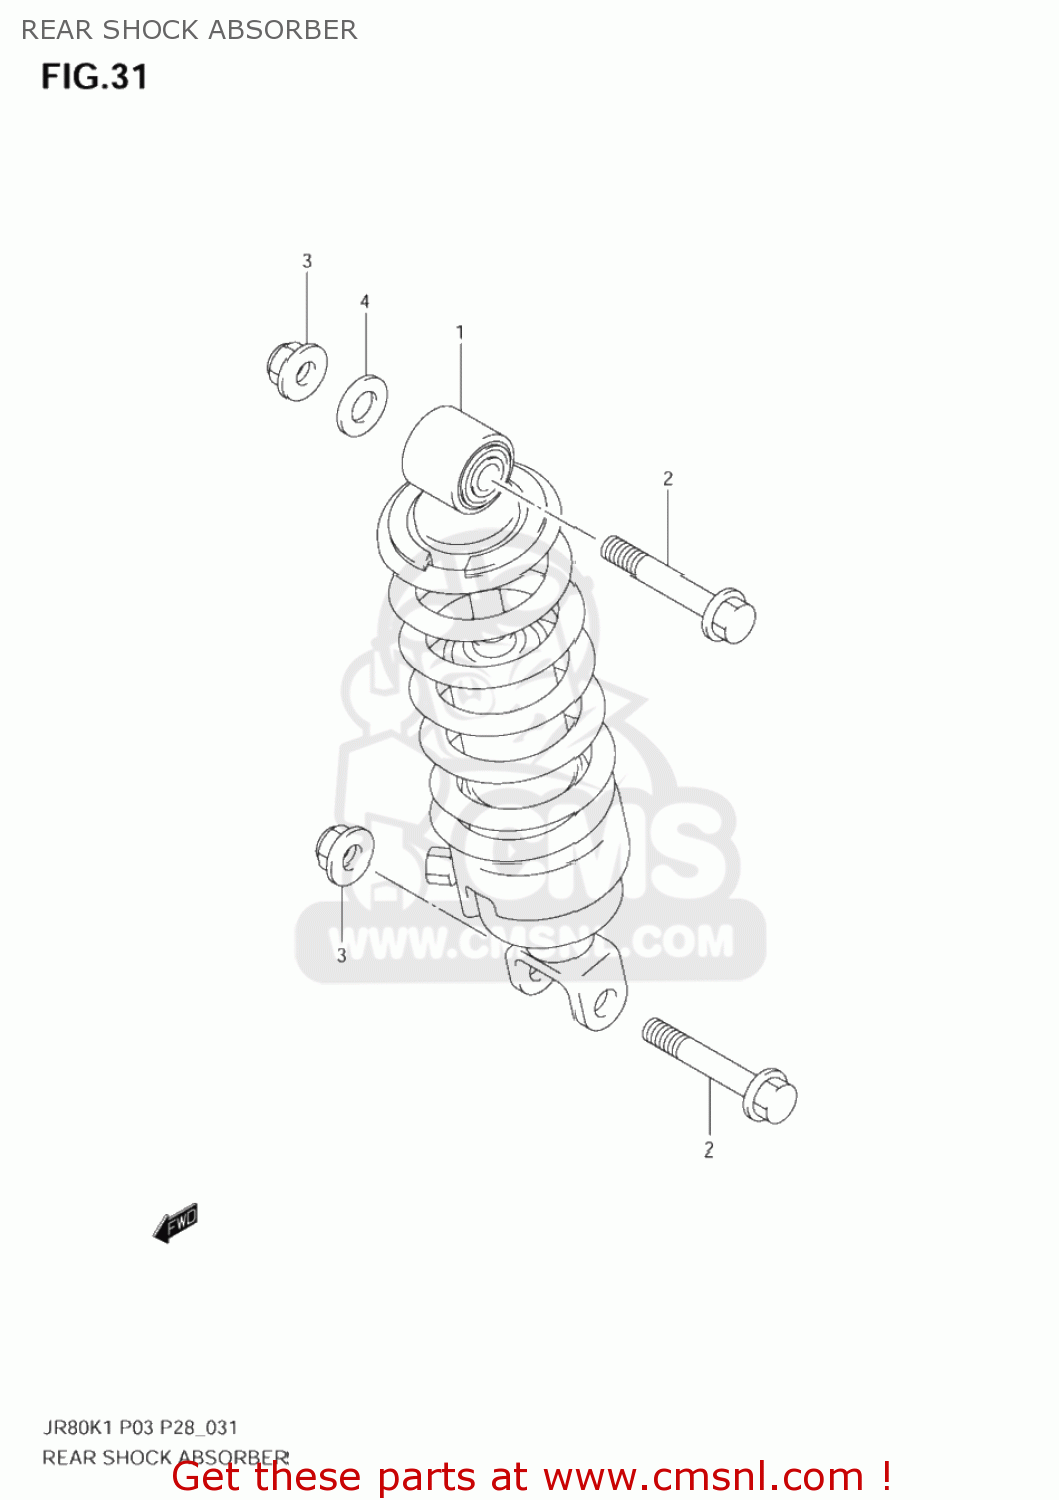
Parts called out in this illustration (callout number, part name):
1	ABSORBER ASSY,RR SHOCK
2	BOLT,RR SHOCK ABSORBER(10X51)
3	NUT
4	WASHER(10.5X22X1.6)
